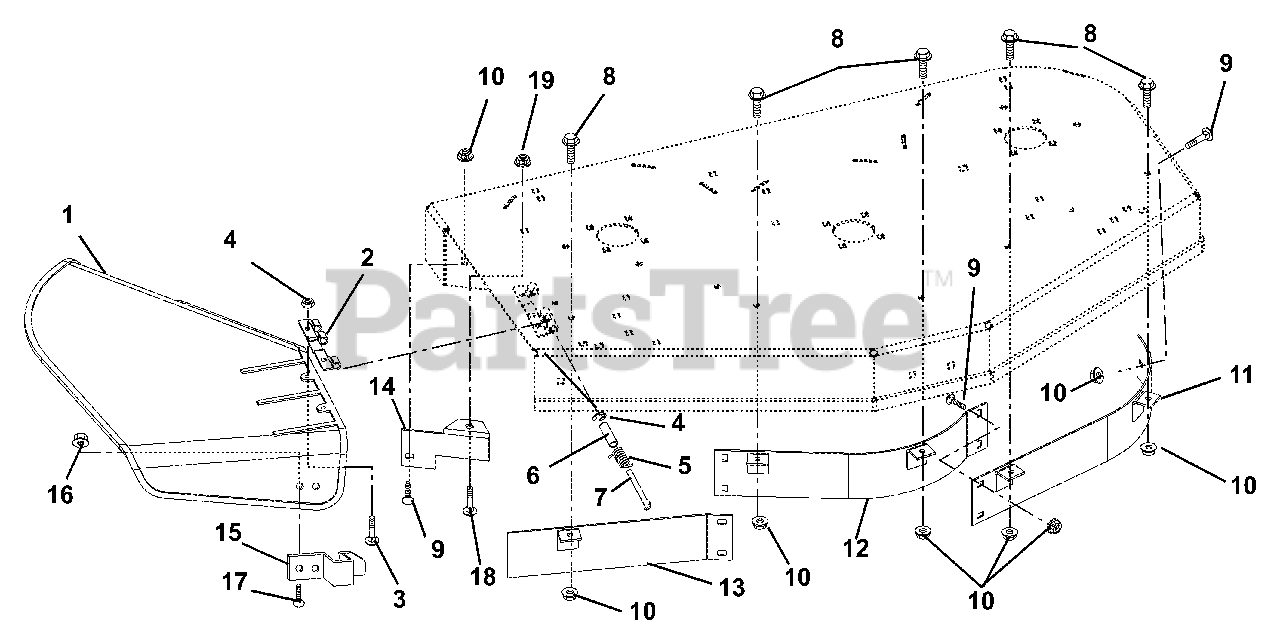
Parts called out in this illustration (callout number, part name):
1	DEFLECTOR, CHUTE
2	HINGE PLATE
3	BLT-RDHDSQNK .25-20X.75 G5YZ
4	RG-RTNG-EXT .312X.025
5	SG-TORS .095X.50X 1.0
6	BSHG-SLV .334 X .502 X 1.437
8	BLT-SERHFWH .312-18X.75 YWZC
9	@BLT-RHDSSQNK .31-18X.75 G5YZ
10	@NUT-LK-NYL-FLG .31-18 YWZC
11	BAFFLE - LEFT FRONT - 40"
12	BAFFLE - CENTER FRONT - 40"
13	BAFFLE - RIGHT FRONT - 40"
14	DEFLECTOR-40"
15	FLAT SPRING
16	NUT-LK-TOP-FLG .25-20 YWZC
17	@BLT-RDHDSQNK .25-20X.50 G5YZ
18	BLT-RDHDSQNK .38-16X1.00 G5YZ
19	@NUT-LK-NYL-FLG .38-16 YWZC
